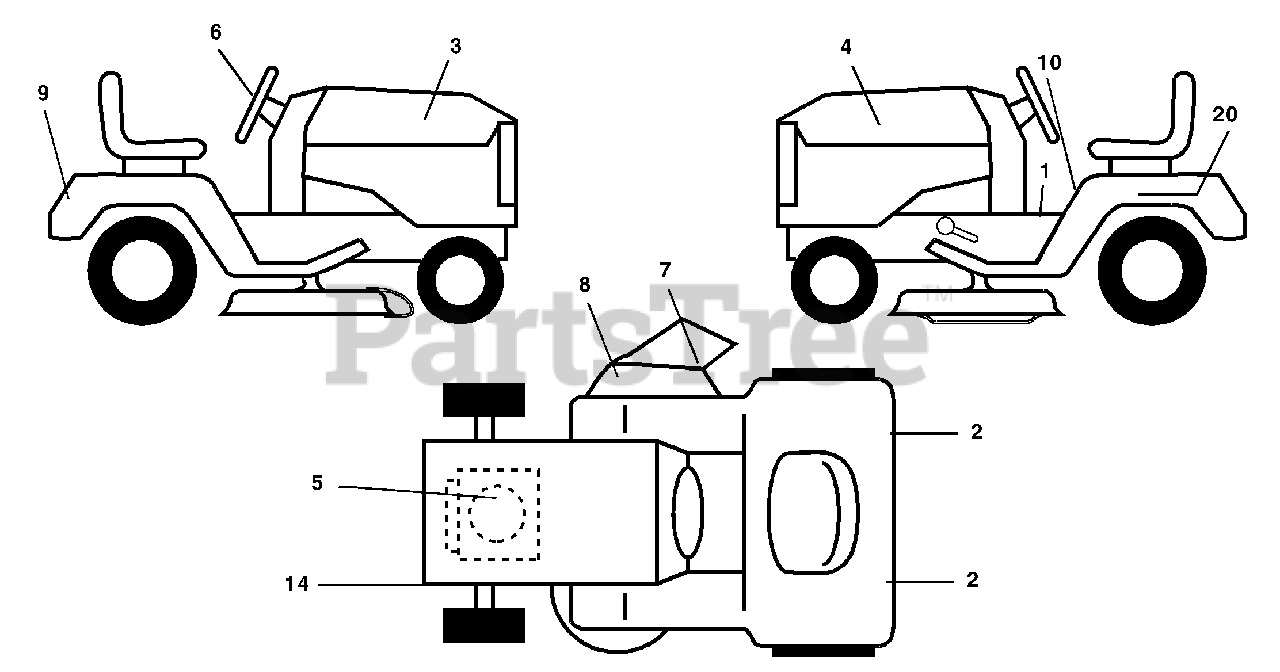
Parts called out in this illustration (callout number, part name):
1	Decal Oper. Step Thru Eng/Fr
2	Reflector Tail Light Red/Amber
3	Decal Hood RH
4	Decal Hood LH
5	Decal Hood Cust.
6	Decal Wheel Steering
7	Decal Deck B 42
8	Decal Warning
9	Decal Fender Husq
10	Decal Fender Danger Eng/Fr
14	Decal V-Belt Schematic
20	Decal Bat Dan/Psn
